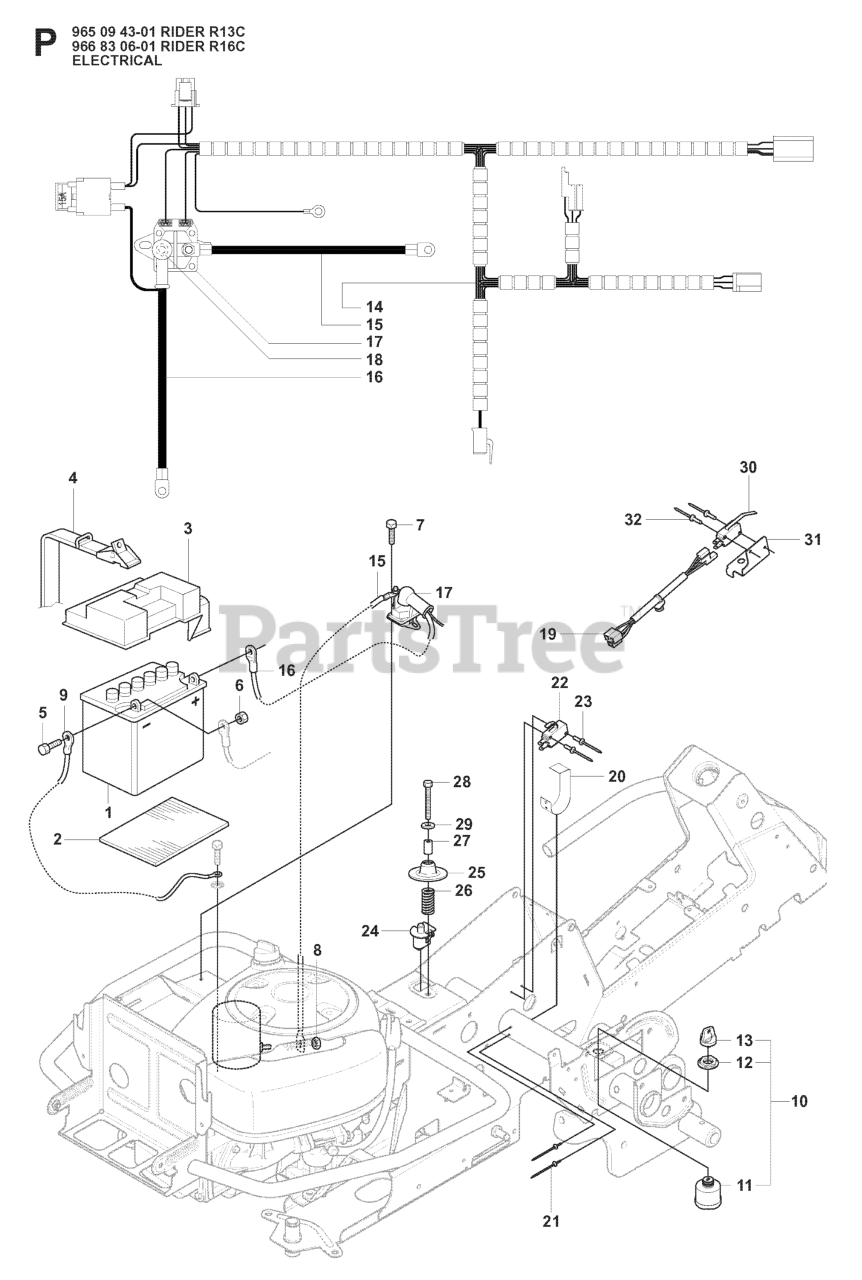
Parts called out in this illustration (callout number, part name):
1	BATTERY - DRY
10	IGNITION SWITCH
11	IGNITION SWITCH
13	IGNITION KEY
19	WIRING
22	%BRAKER
27	SPACER TUBE
28	SCREW
29	WASHER BRB 8.4X17
30	RP MICRO SWITCH
